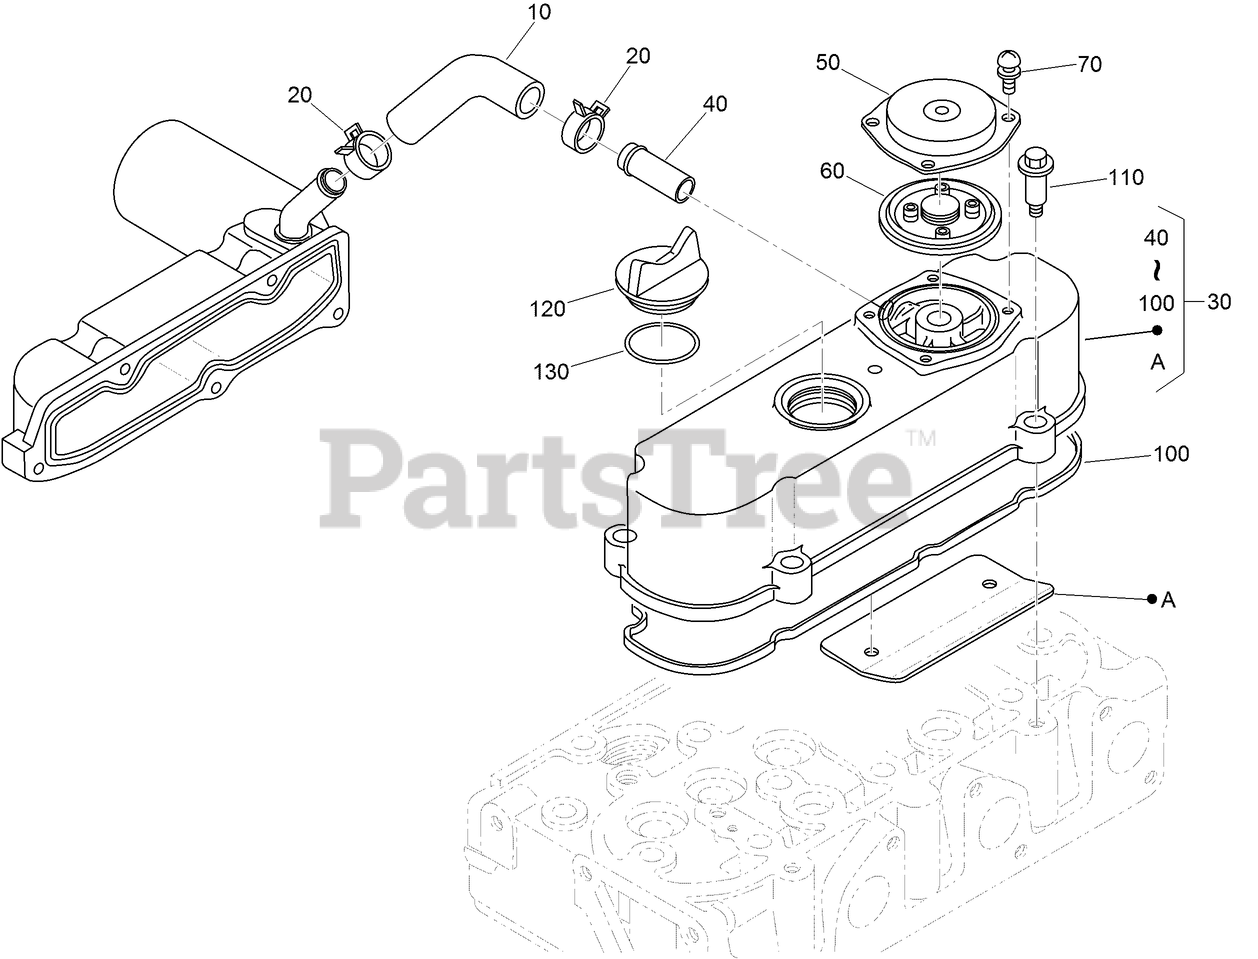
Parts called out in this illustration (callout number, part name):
10	TUBE-BREATHER
20	CLAMP-HOSE
30	CYLINDER HEAD COVER ASM
40	PIPE-RETURN, WATER
50	COVER-BREATHER
60	VALVE-BREATHER
70	SCREW (WITH WASHER)
100	GASKET-COVER, HEAD
120	PLUG-FILLER, OIL
130	O-RING
